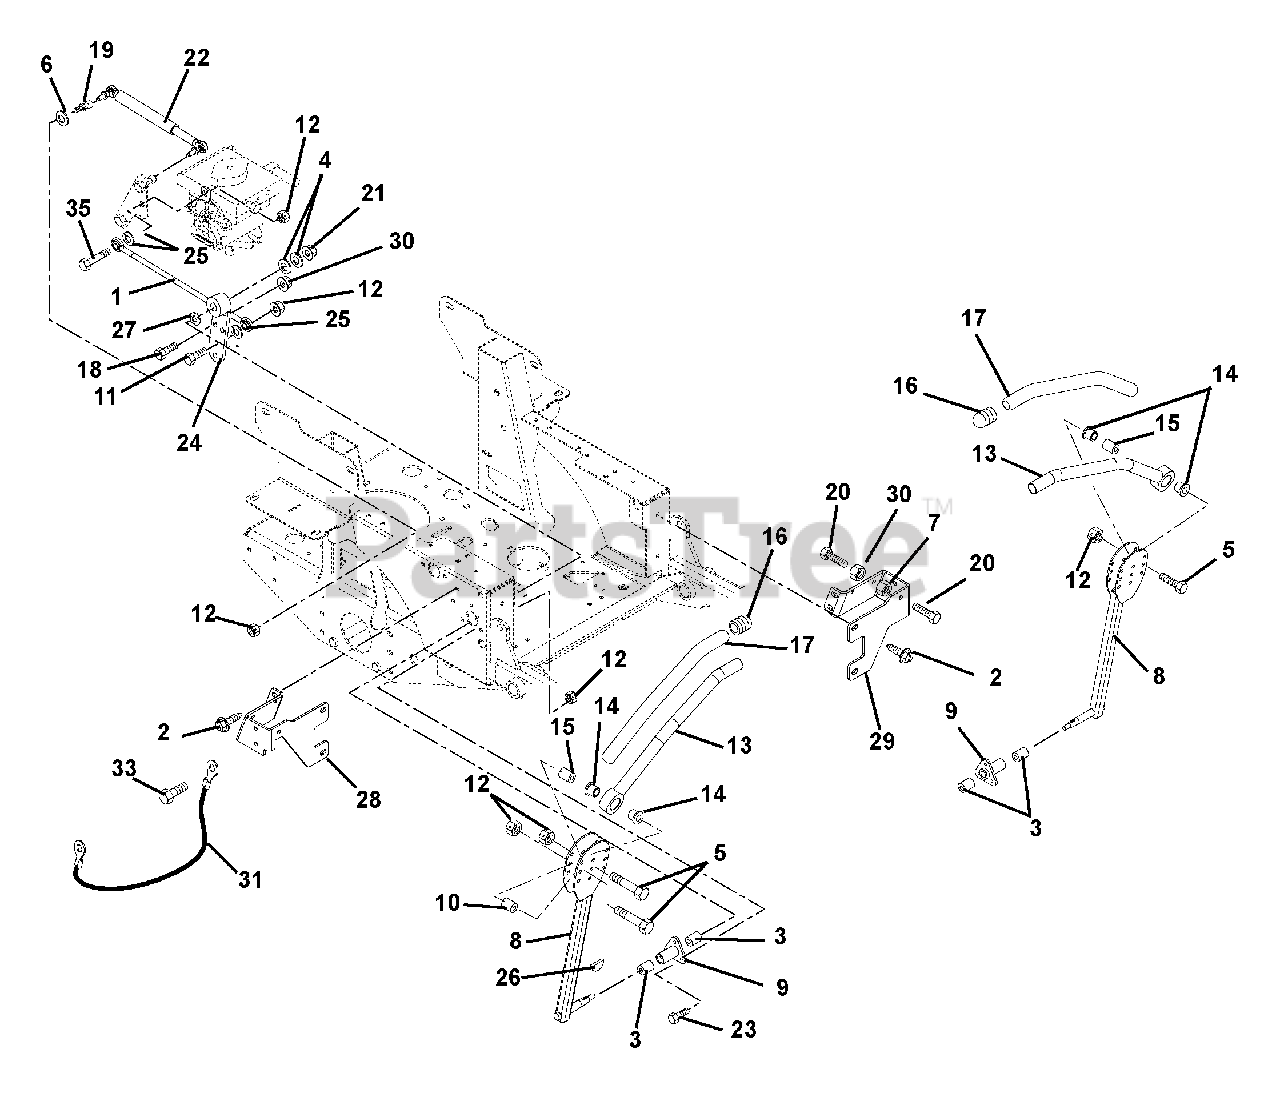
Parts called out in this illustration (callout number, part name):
1	Assembly, Steering Rod
2	Screw, Tapping .38-16 x .75 Hex Washer Head
3	Bushing .625 x .75 x .50
4	Washer, Flat Steel .406 x .812 x .065
5	Bolt, Hex .31-18 x 1.75 Grade 5
6	Washer, Flat Steel .344 x .688 x .065
7	Nut, Hex Jam .375-16
8	Control Arm
9	Housing, Bushing
10	Eccentric
11	Bolt, Hex .31-18 x 1.25 Grade 5
12	Nut, Nyloc Flange 3/8-18
13	Handle Weldment Left-Hand
13	Handle Weldment Right-Hand
14	Bushing, Flange Nylon .762 x 1.48 x .44
16	Caplug, Handlebar
17	Grip, Handlebar
18	Bolt, Hex .375-16 x 1.75
19	Stud, Ball
20	Bolt, Hex .38-16 x 1.25 Grade 5
21	Nut, Nyloc Flange 3/8-16
23	Bolt, Hex .31-18 x 1.00 Grade 5
24	Weldment, Pivot Arm
25	Washer, Locking .31 x .078 Regular
26	Key, Woodruff .13 x .63
27	Wave Washer
28	Stop, Steering-Right Hand
29	Stop, Steering-Left Hand
30	Nut, Locking Jam Center .375-16
31	Cable, Hood
32	Washer, Flat Steel .265 x .50 x .087
33	Bolt-Hex .25-20 x .75 Grade 5
34	Nut, Nyloc Flange .25-20
35	Bolt, Hex .31-18 x 1.50 Grade 5
